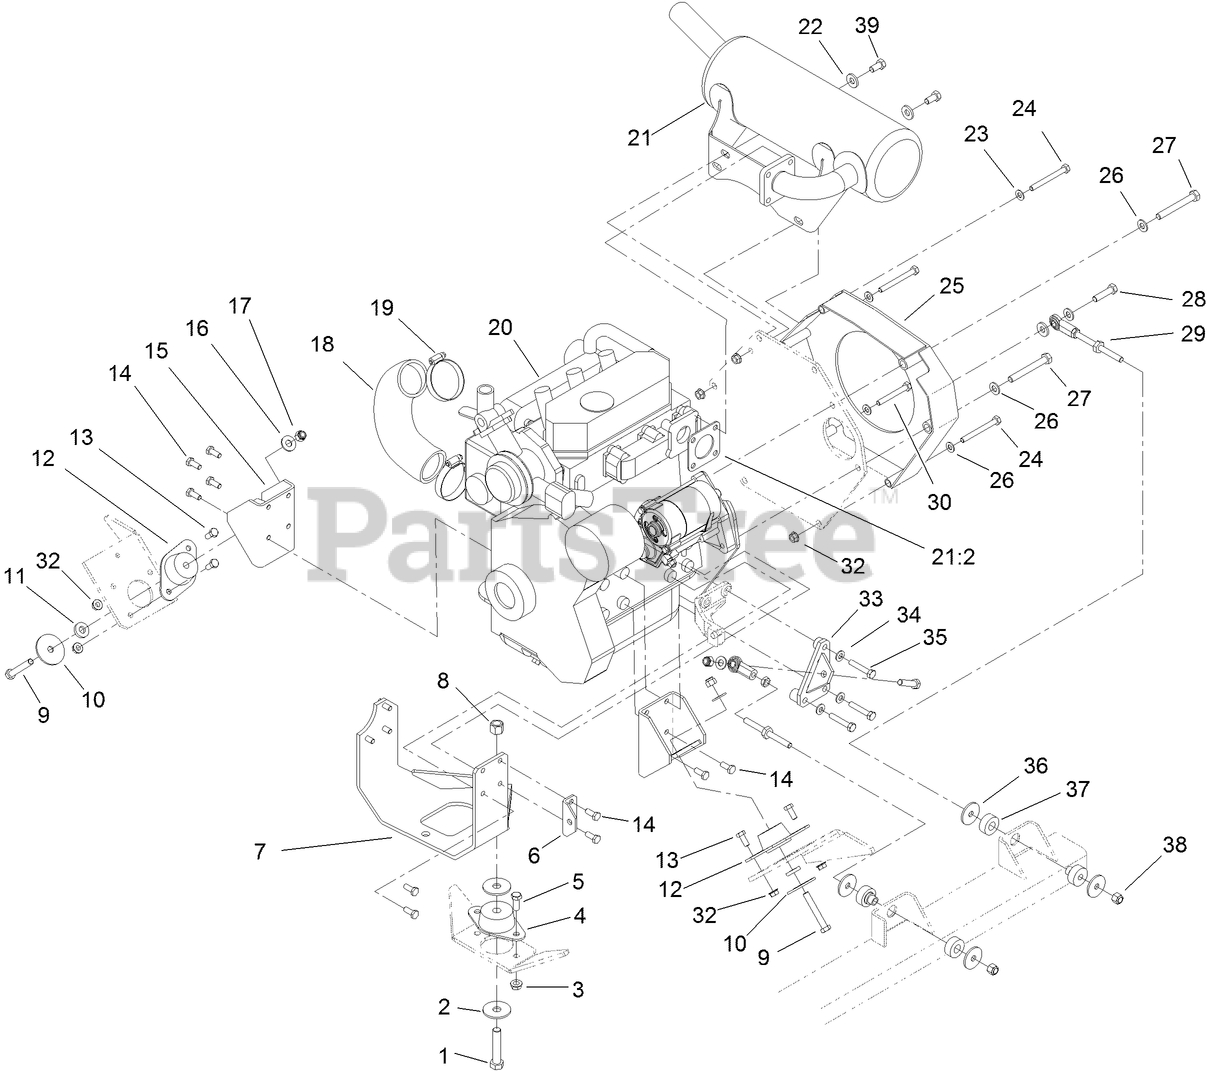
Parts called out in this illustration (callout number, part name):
1	SCREW-HH
2	WASHER-THRUST
3	NUT-HHF, WHIZ
4	ISOLATOR-REAR
5	SCREW-HH
6	BRACKET-GROUND
7	REAR ENGINE MOUNT ASM
8	NUT-LOCK, NI
9	SCREW-HH
10	WASHER-FLAT
11	WASHER
12	ISOLATOR-SIDE
13	SCREW-HH
14	SCREW-HH
15	LH AND RH ENGINE MOUNT ASM
16	WASHER-FLAT
17	NUT-LOCK, NI
19	CLAMP-HOSE
21	MUFFLER KIT
21:2	GASKET-MUFFLER
22	WASHER-BELLEVILLE
23	WASHER-PLAIN
24	SCREW-HH
25	COVER-FLYWHEEL
26	WASHER-FLAT
27	SCREW-HH
28	SCREW-HH
29	BALL JOINT LINK ASM
30	SCREW-HH
32	NUT-HF
33	BRACKET-ENGINE, FRONT
34	WASHER-SPRING
35	SCREW-HH
36	WASHER
37	ISOLATOR-LINK
38	NUT-LOCK
39	SCREW-CAP
